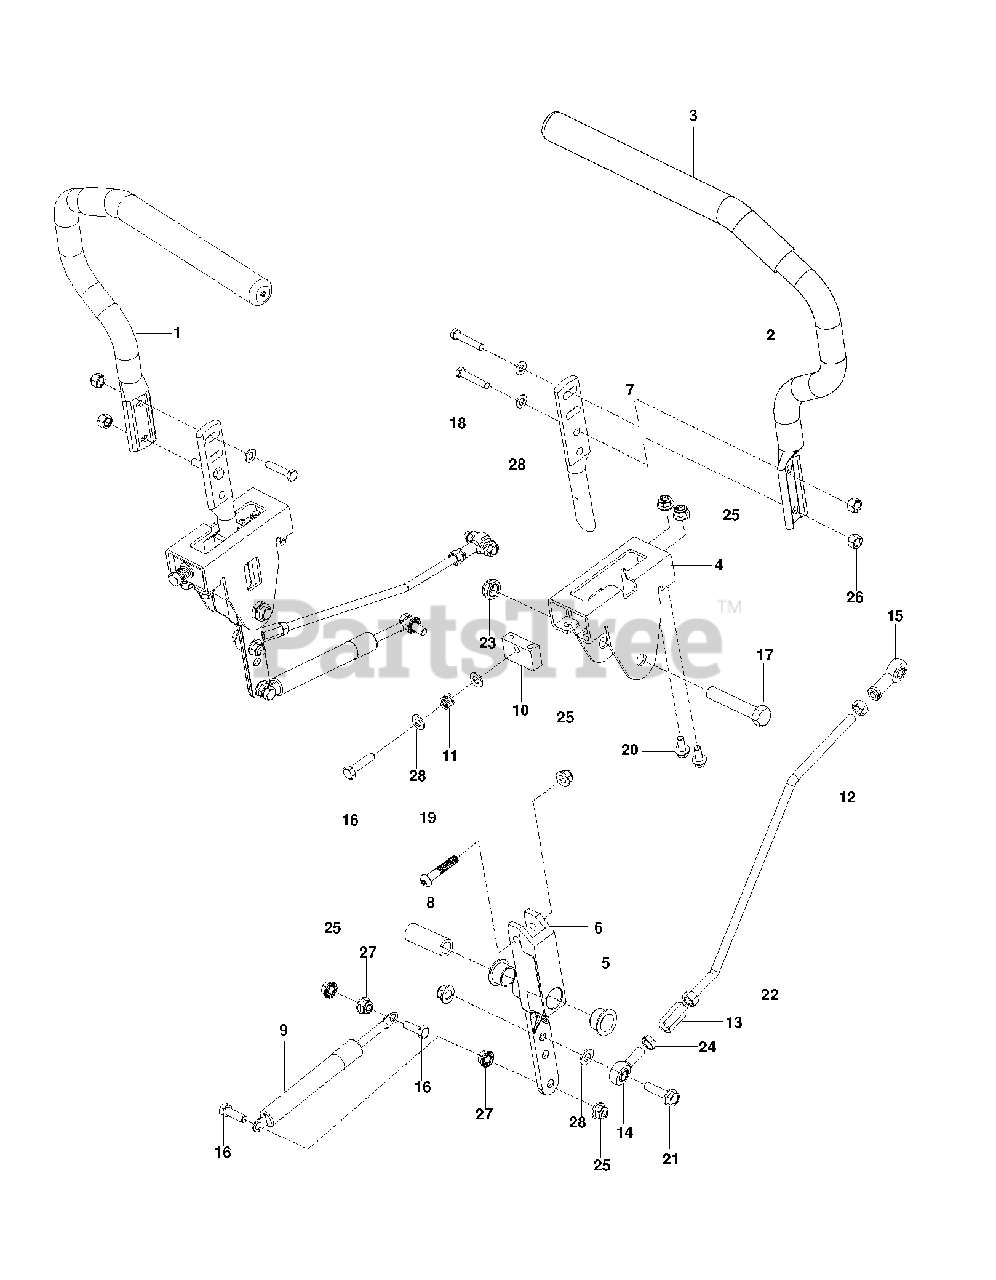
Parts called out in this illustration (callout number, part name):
1	LEVER DRIVE W/GRIP RT
2	LEVER, DRIVE W/GRIP LT
3	GRIP - DRIVE LEVER
4	BRACKET, CONTROL
5	BEARING, FLANGE
6	LEVER CONTROL PIVOT
8	SPACER, PIVOT CONTROL
9	DAMPENER
10	BLOCK, TRACKING
12	ROD, CONTROL
13	ROD END COUPLER
14	RH ROD END
15	ROD END LH
16	HCS 5/16C X 1 1/4
17	HCS 1/2C X 2 3/4
18	CAPSCREW 5/16 X 1/1/2 HEX HEAD
20	HHFS 5/16-18 X 3/4
21	HHFS 5/16-18 X 1.25 TPBLT GD 5
22	NUT 5/16F
23	NUT 1/2-13 HEX JM NYL
24	NUT 5/16F LEFTHAND
25	5/16-18 NYLOC FLANGE NUT
26	NUT 5/16 NYLOC
27	NUT 5/16C WHIZ
28	FLAT WASHER 5/16 SAE
